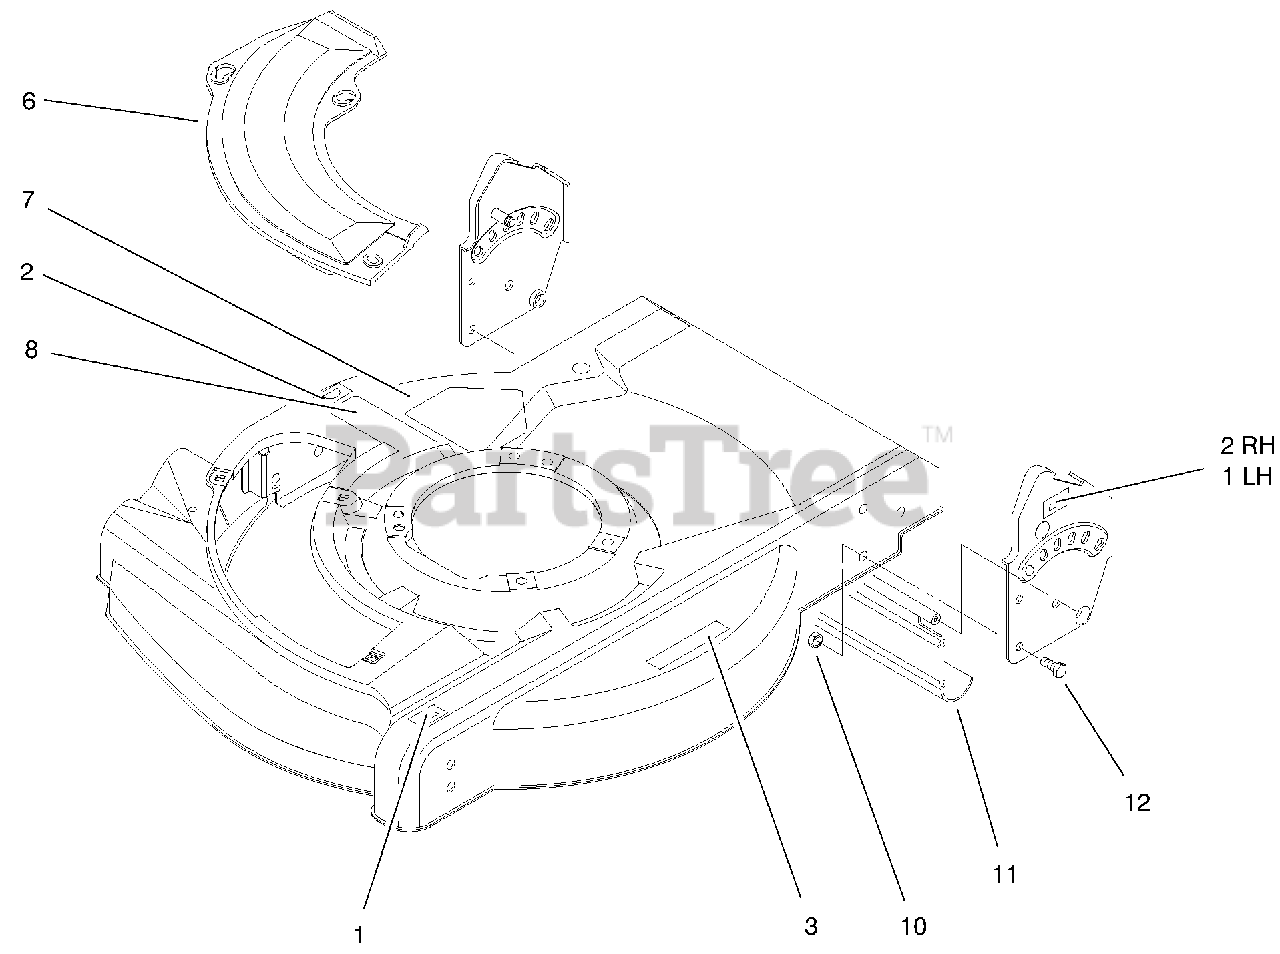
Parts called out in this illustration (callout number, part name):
1	Decal-HOC
2	Decal-HOC
3	Decal-Warning
6	Plate-Cover
7	Decal-Danger
8	Decal-Discharge
10	Nut-Lock
11	Shield-Trailing
12	Screw-HH
